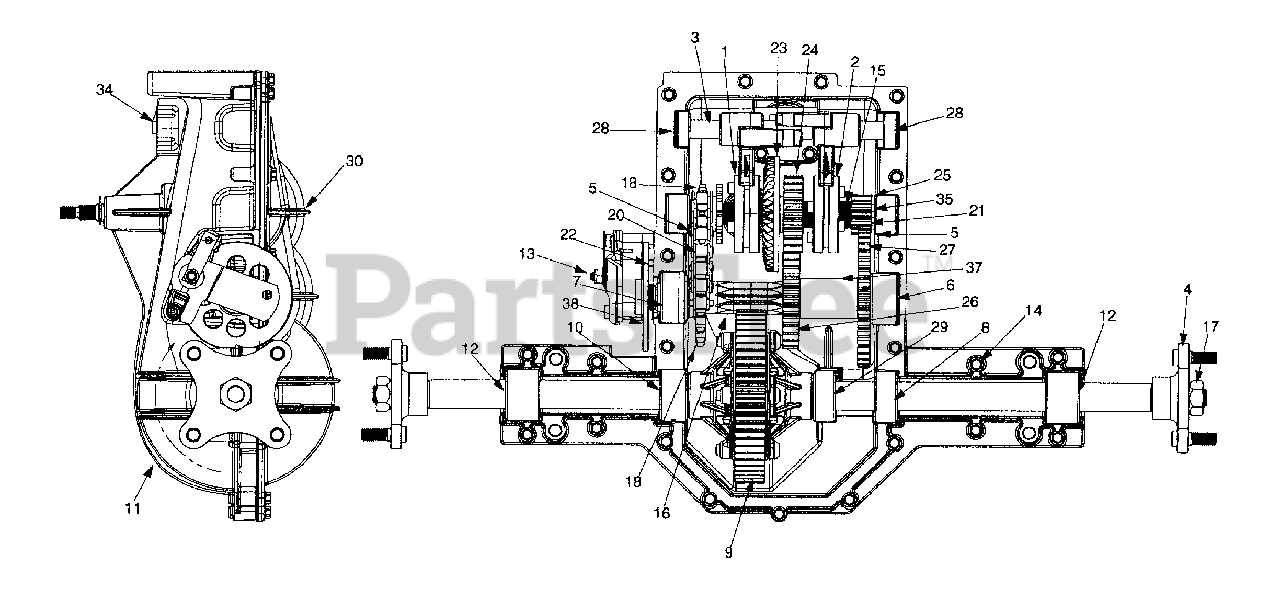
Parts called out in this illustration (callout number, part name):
1	Collar Assembly-Reverse
2	Collar Assembly-Hi-Lo
3	Shift Fork Assembly
4	Wheel Hub Assembly
5	Drive Shaft Blk. Assembly
6	Output Brg. Blk. Assembly
7	Output Brg. Blk. Seal
8	Inboard Axle Blk. Assembly
9	Differential Axle Assembly
10	Inboard Axle Blk. Assembly
11	Upper Housing Assembly
12	Axle Brg. Blk. Assembly
13	Bracket Assembly -R.H.
14	TT Tap Scr. 1 /4-20 x 1"
15	Drive Shaft
16	Output Shaft -R.H.
17	Hex Nut 3/4-16
18	Sprocket 9T
20	Chain Endless
21	Ext. Snap Ring
22	Brake Pad
23	Bevel Gear 41 T
24	Spur Gear 20T
25	Spur Gear 10T
26	Spur Gear 27T
27	Spur Gear 37T
28	Shifter Brg. Blk.
29	Inner Axle Blk. Brg.
30	Lower Housing
34	Shipping Plug
35	Fl-Wash. 5/8" I.D. x 1" O.D.
37	Spacer 1.13" I.D. x 1.38" O.D.
38	Disc Brake
